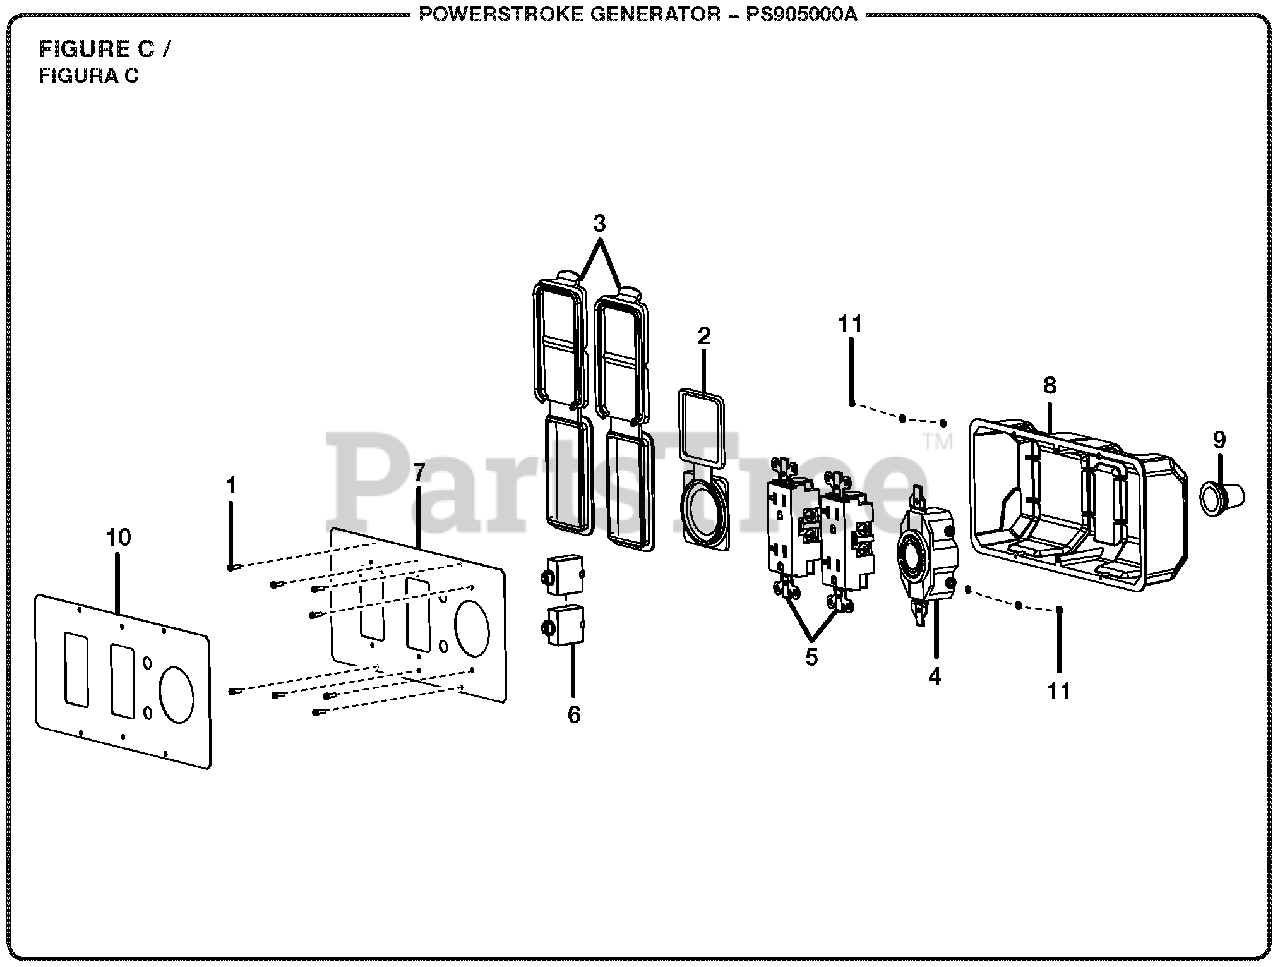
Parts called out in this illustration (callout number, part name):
1	Screw (#6-20 x .38 in.)
2	Outlet Cover (240 Volt)
3	Outlet Cover (120 Volt)
4	Twist Lock Receptacle (240 Volt)
5	Duplex Receptacle (120 Volt)
6	Circuit Breaker (20 Amp)
7	Front Panel
8	Control Box (Back Panel)
9	Rubber Sleeve
10	Front Panel Label
11	Lock Nut (#6- 32)
